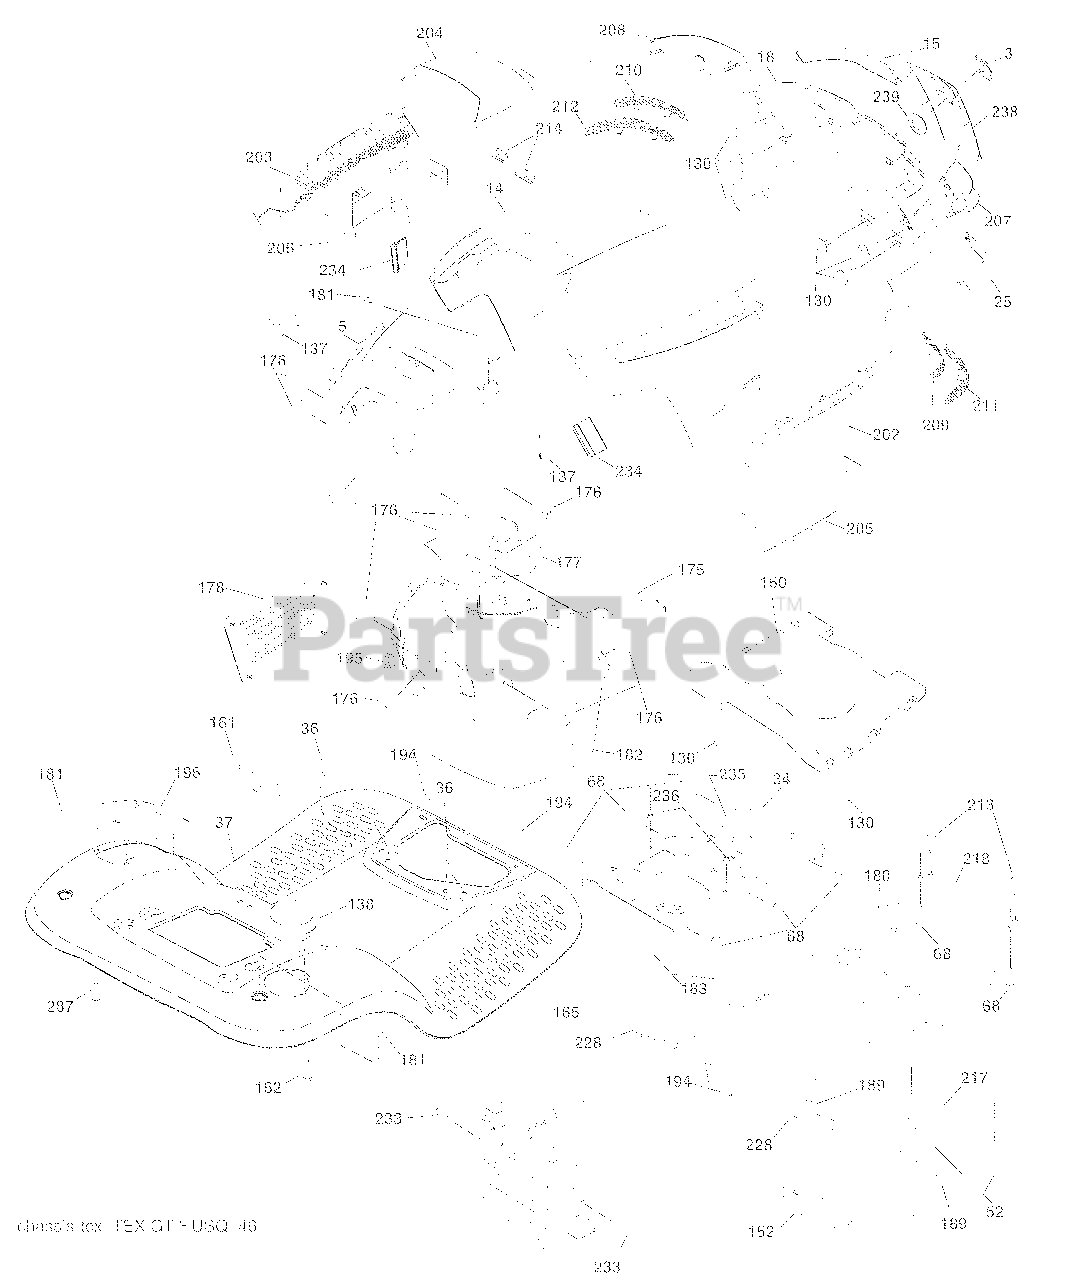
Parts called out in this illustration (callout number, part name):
3	Logo
14	Hood
18	Grille Asm.
34	Plate Engine
36	Screw 5/16-18 x 3/4
52	Nut Lock 5/16-18
68	Screw 5/16-18 x 1/2
130	Screw #10 x 0.750 BOS Thread
137	Bumper Dash
138	Cupholder
152	Shield Browning
161	Window Fuel
165	Support Tank Rear
175	Crossmember
176	Screw 10-24 x 5/8
177	Bushing Steering
178	Cargo Net Asm.
180	Chassis
181	Bushing Mtg. Fender Crgo
182	Dash Lower
183	Bolt Fin Hex 5/16-18 unc x 1-1/4
189	Screw 5/16-18 x 3/4
194	Nut Lock Hex Flange 5/16-18
195	Plug Hole Dash Lower
196	Console Asm. Deck Lift
202	Vent Side Hood RH
203	Vent Side Hood LH
204	Vent Top Hood
205	Skirt Hood Side RH
206	Skirt Hood Side LH
209	Insert Hex Top RH
210	Insert Hex Top LH
211	Insert Hex Bottom RH
212	Insert Hex Bottom LH
213	Bolt 5/16-18 unc x 3/4
214	Clip Retainer Tinner
218	X-Piece Hood Stop
228	Stud Fastner
233	Bolt, Shoulder
234	Bumper Hood
235	Spacer Fender
236	Nut Lock 5/16-18 unc
287	Screw Hex Washead 1/4-20 x 3/8
